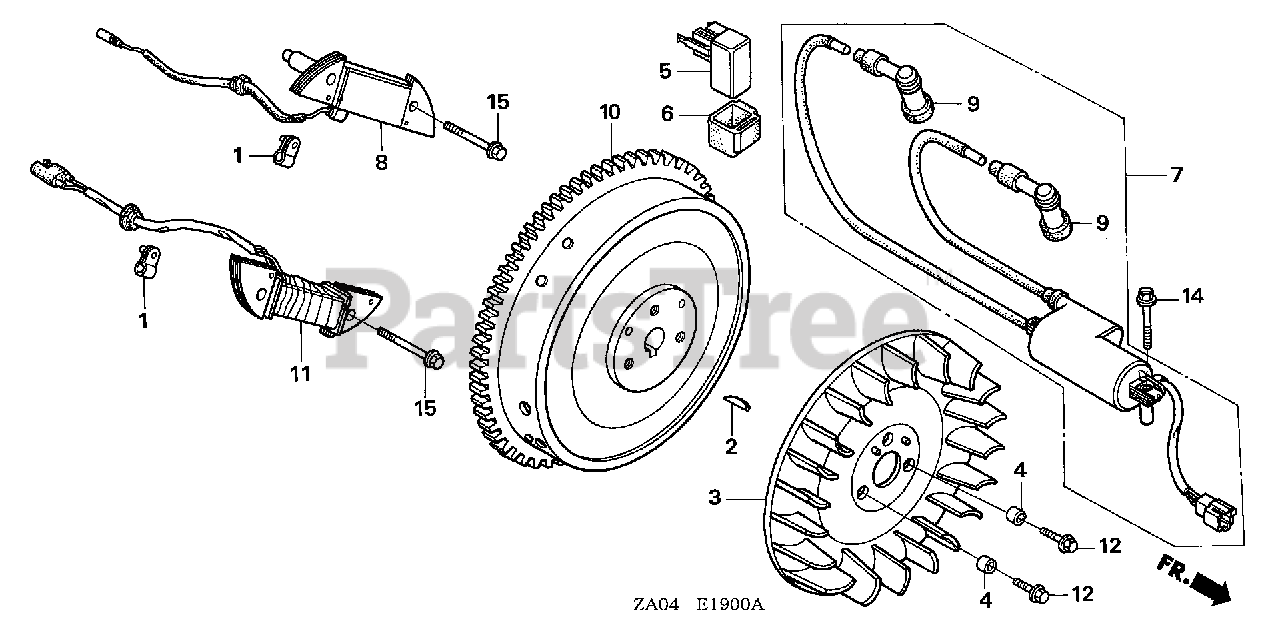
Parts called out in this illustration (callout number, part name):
1	CLAMP, CHARGE COIL (NOT AVAILABLE)
2	KEY, SPECIAL WOODRUFF (25X18)
3	FAN, COOLING
4	COLLAR, FAN
5	MODULE, IGNITION CONTROL (CDI)
6	CUSHION, IGNITION CONTROL MODULE (CDI)
7	COIL ASSY., C.D.I. IGNITION (NOT AVAILABLE)
8	COIL ASSY., EXCITER (NOT AVAILABLE)
9	CAP ASSY., NOISE SUPPRESSOR
10	FLYWHEEL (NOT AVAILABLE)
12	BOLT, FLANGE (6X16)
14	BOLT, FLANGE (6X45)
15	BOLT, FLANGE (6X50)
